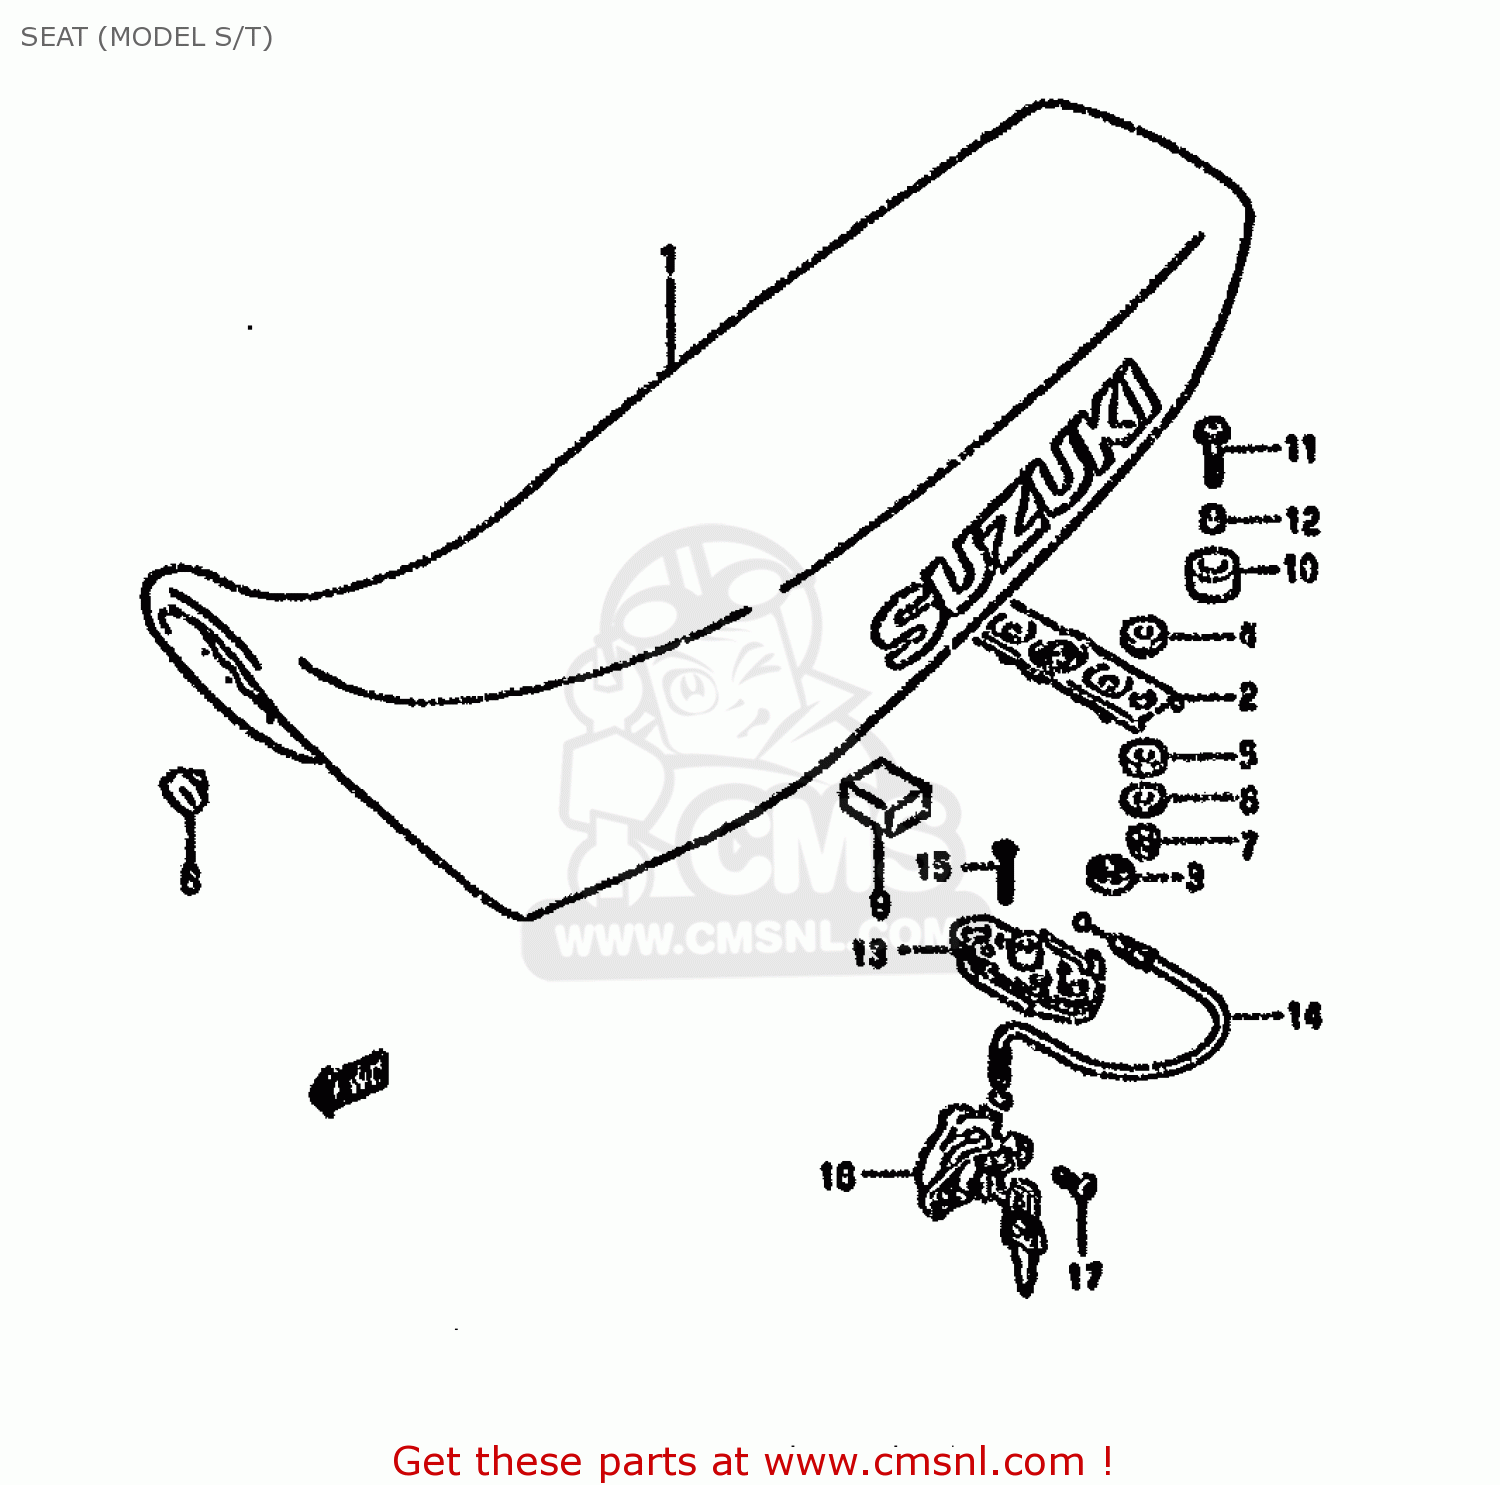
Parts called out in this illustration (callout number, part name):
1	SEAT SET
2	STRIKER,SEAT LOCK
3	CUSHION,SEAT LOCK(10X22X6)
4	CUSHION,UPR
5	CUSHION,LWR
6	WASHER
7	NUT
8	CUSHION
9	CUSHION,TOOL(40X30X15)
10	CUSHION,COVER
11	SCREW
12	SPACER (6.1X8X8)
13	BRACKET,SEAT SUPPORT,RIGHT
14	CABLE,SEAT LOCK
15	SCREW
16	LOCK SET,SEAT
17	SCREW
